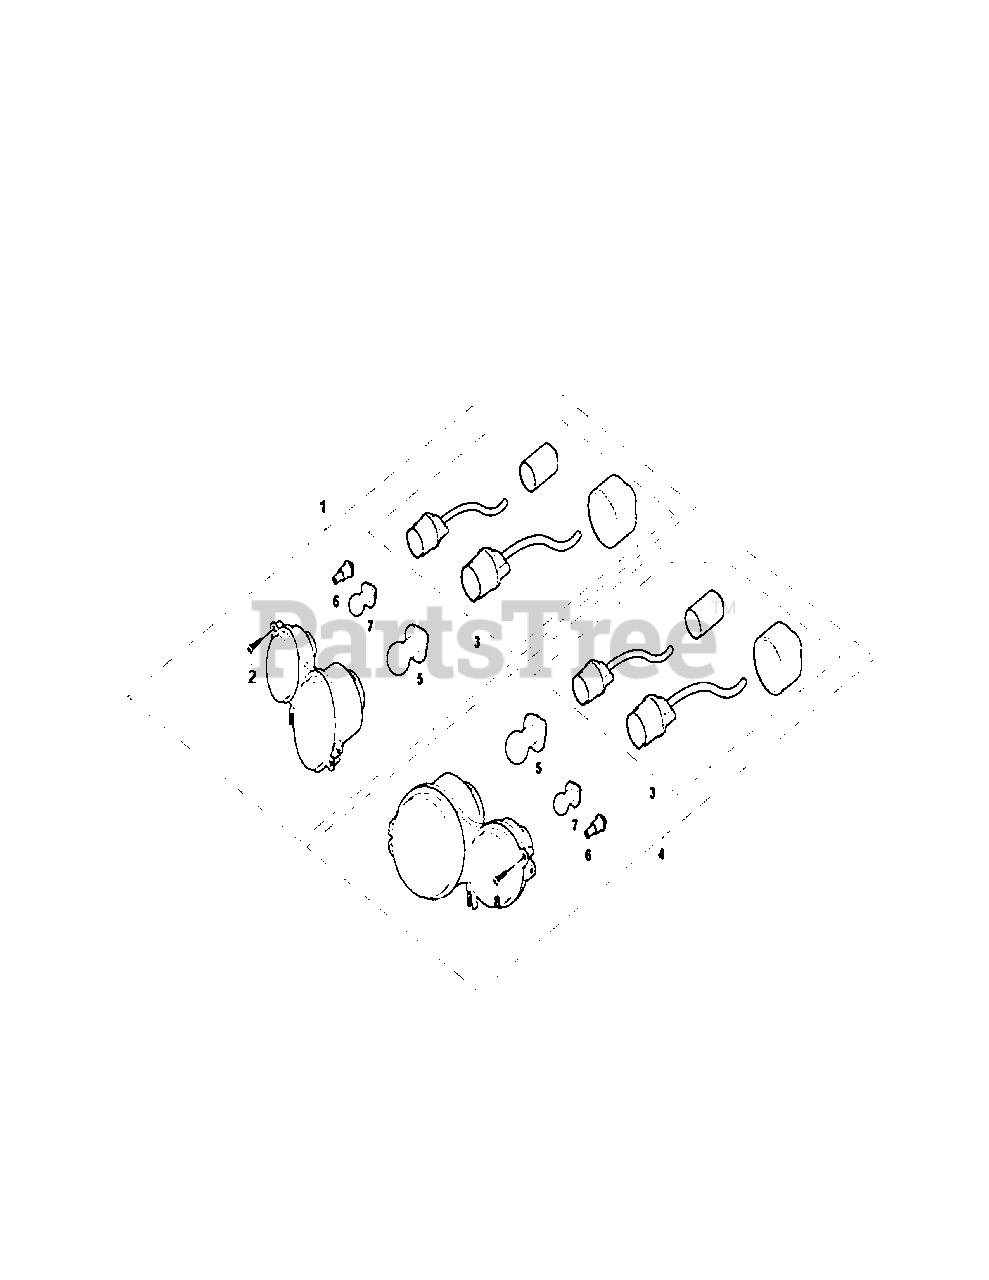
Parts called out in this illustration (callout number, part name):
1	Right Headlight Assy (Model A)
2	Cross Recessed Plate Head Tapping Screws ST3.5×9.5
3	Headlight Cable
4	Left Headlight Assy (Model A)
5	Front Headlight Bulb (12V 35W/35W)
6	Position Light Bulb (12V 5W)
7	Front Turninglight Bulb (12V 10W)
